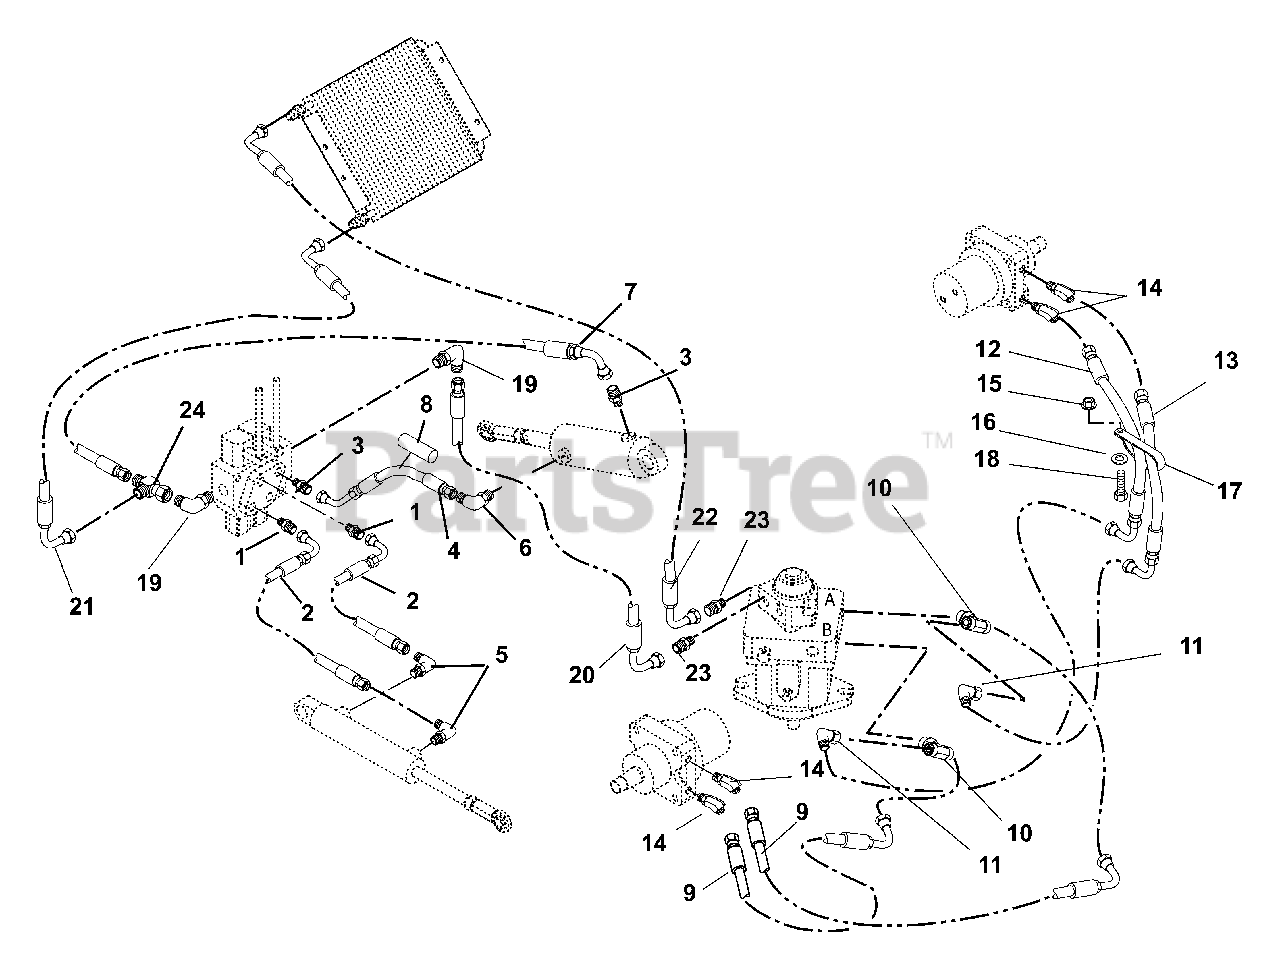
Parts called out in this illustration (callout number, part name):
1	Fitting, Hydraulic
2	Hose, Hydraulic
3	Fitting, Hydraulic
4	Hose, Hydraulic
5	Fitting, Hydraulic
6	Fitting, Hydraulic
7	Hose, Hydraulic
8	Sleeve 12"
9	Hose, Pump To Motor, .50-22-2K F08F0-F08F9
10	Fitting, Hydraulic Tee, M80-M80-M80
11	Fitting, Hydraulic 90 EL
12	Hose, Pump To Motor .50-26-2K F08F0-F08F9
13	Hose, Hydraulic .50-24-2K F08F0-F08F9
14	Fitting, Hydraulic
15	Nut-Locking-Top-Flange .38-16
16	Washer-Flat-Steel .406 x .812 x .065
18	Bolt-Hex .38-16 x 1.00 Grade 5
19	Fitting, Hydraulic Elbow
20	Hose, Hydraulic
21	Hose, Hydraulic
22	Hose, Hydraulic
23	Fitting, Hydraulic
24	Fitting, Hydraulic
